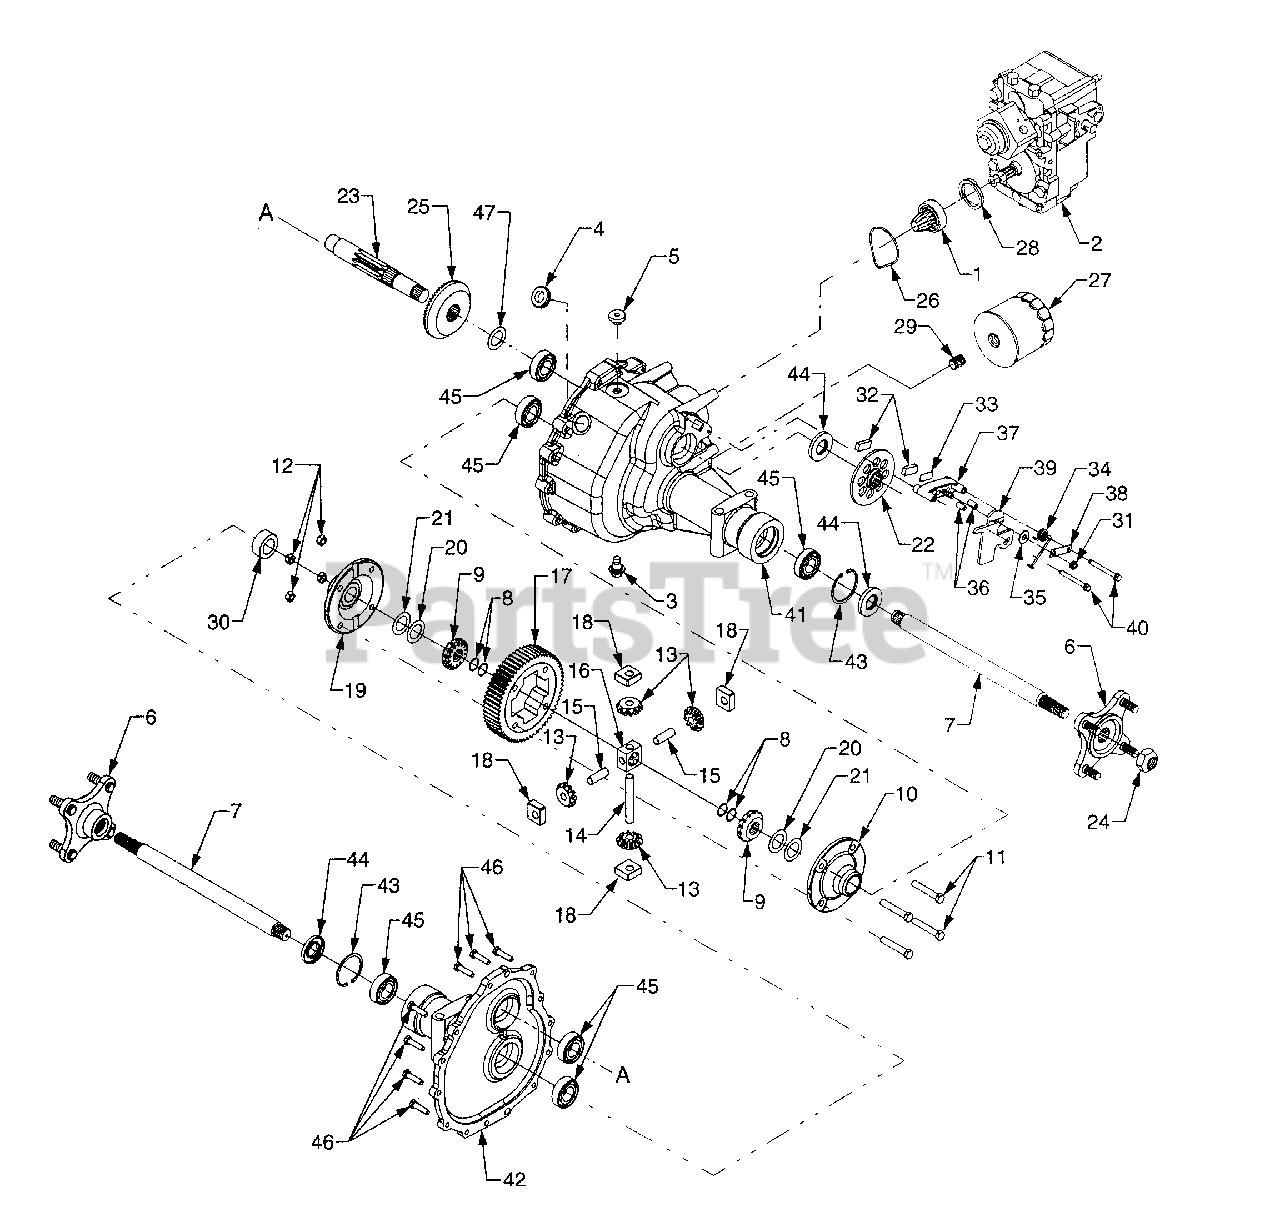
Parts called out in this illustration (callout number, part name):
1	Gear Assembly, Pinion 13T.
2	Hydrostatic Transmission Assy.
3	Plug, Drain, M14 x 1.5 x .827
4	Grommet, Rubber
6	Hub Assembly, Wheel
7	Axle Shaft,
8	Retaining Ring
9	Gear, Spur, 14T
10	Housing, Diff. Cover RH
11	Hex Cap Screw, 3/8-24 x 2.25 GR5
12	Nut, Hex Lock, 3/8-24
13	Gear, Differential 10T
14	Shaft, Cross, .5 x 3.485
15	Shaft, Cross, Special
16	Differential Pinion Block
17	Gear, Spur 60T
18	Block, Thrust Miter
19	Housing, Differential Cover LH
20	Washer, Flat, 1.0 x 1.56 x .040
21	Washer, Flat, 1.0 x 1.56 x .020
22	Disc, Brake
23	Shaft, Output 9T
24	Nut, Lock, 3/4-16
25	Gear, Bevel 54T
26	Seal, Gland O-Ring
27	Filter, Oil
28	Washer, Spring
29	Fitting, Filter Nipple
30	Spacer, Axle, 1.0 x 1.665 x .71
31	Nut, Hex Insert Lock, 5/16-24
32	Pad, Brake
33	Plate, Puck
34	Spring, Torsion
35	Washer, Flat, .343 x .88 x .062
36	Pin, Brake Actuator
37	Yoke, Brake
38	Bracket, Brake Anti-Rotation
39	Arm, Brake Actuator
40	Screw, Hex Wash. Hd. Tapp 1/4-20 x 2.375
41	Housing, RH
42	Housing, LH
43	Retaining, Ring
44	Seal, Oil, 1.0 ID
45	Bearing, Ball
46	Screw, Hex Cap Locking 5/16-18 x 1.25 GR5
47	Washer, Flat, 1.0 x 1.56 x .030
